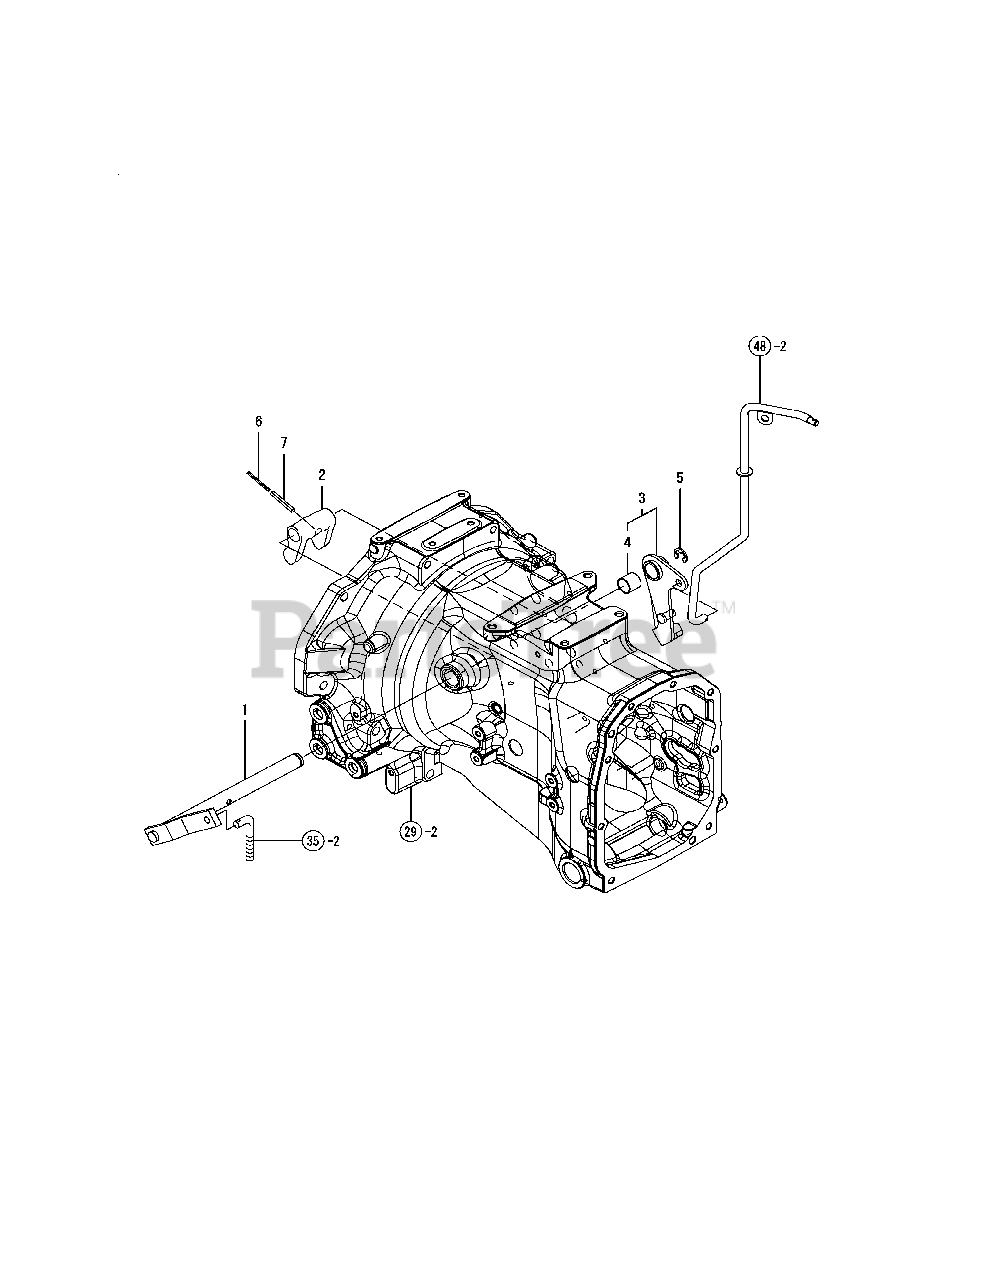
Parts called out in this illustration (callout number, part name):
1	SHAFT, RELEASE
2	YOKE, CLUTCH RELEASE
3	PLATE, CRUISE ASSY
4	BUSH 20X20,DRY
6	SPRING PIN 3.5X40
7	SPRING PIN 6X40
